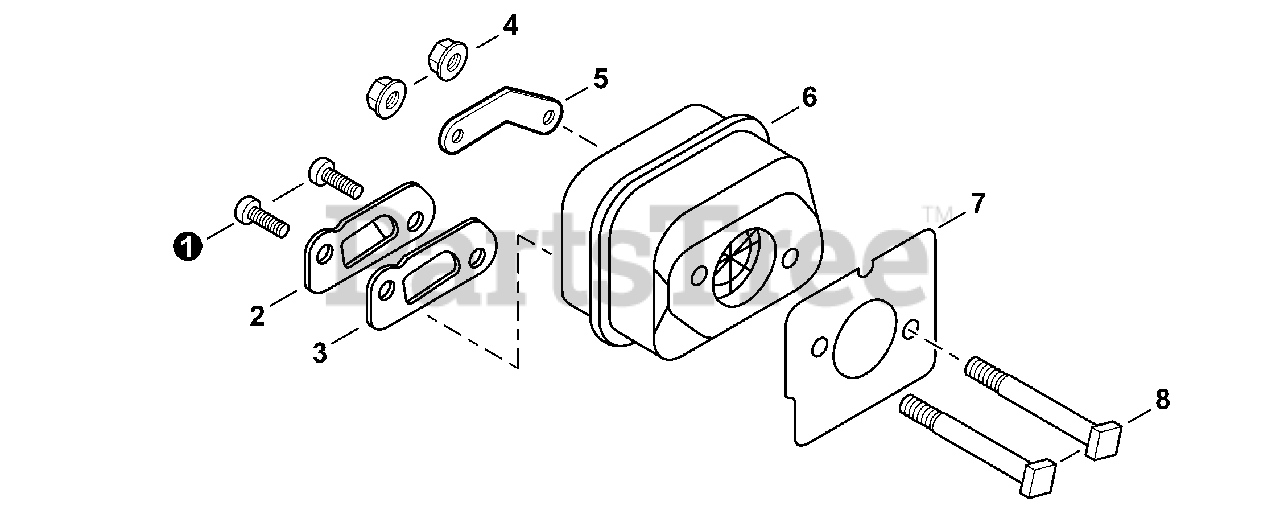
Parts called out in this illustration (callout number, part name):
1	SCREW 4×8
2	GUIDE, EXHAUST
3	SCREEN, SPARK ARRESTER
4	NUT, FLANGE M5
5	PLATE, EYE
6	MUFFLER
7	GASKET, EXHAUST
8	BOLT 5×62
